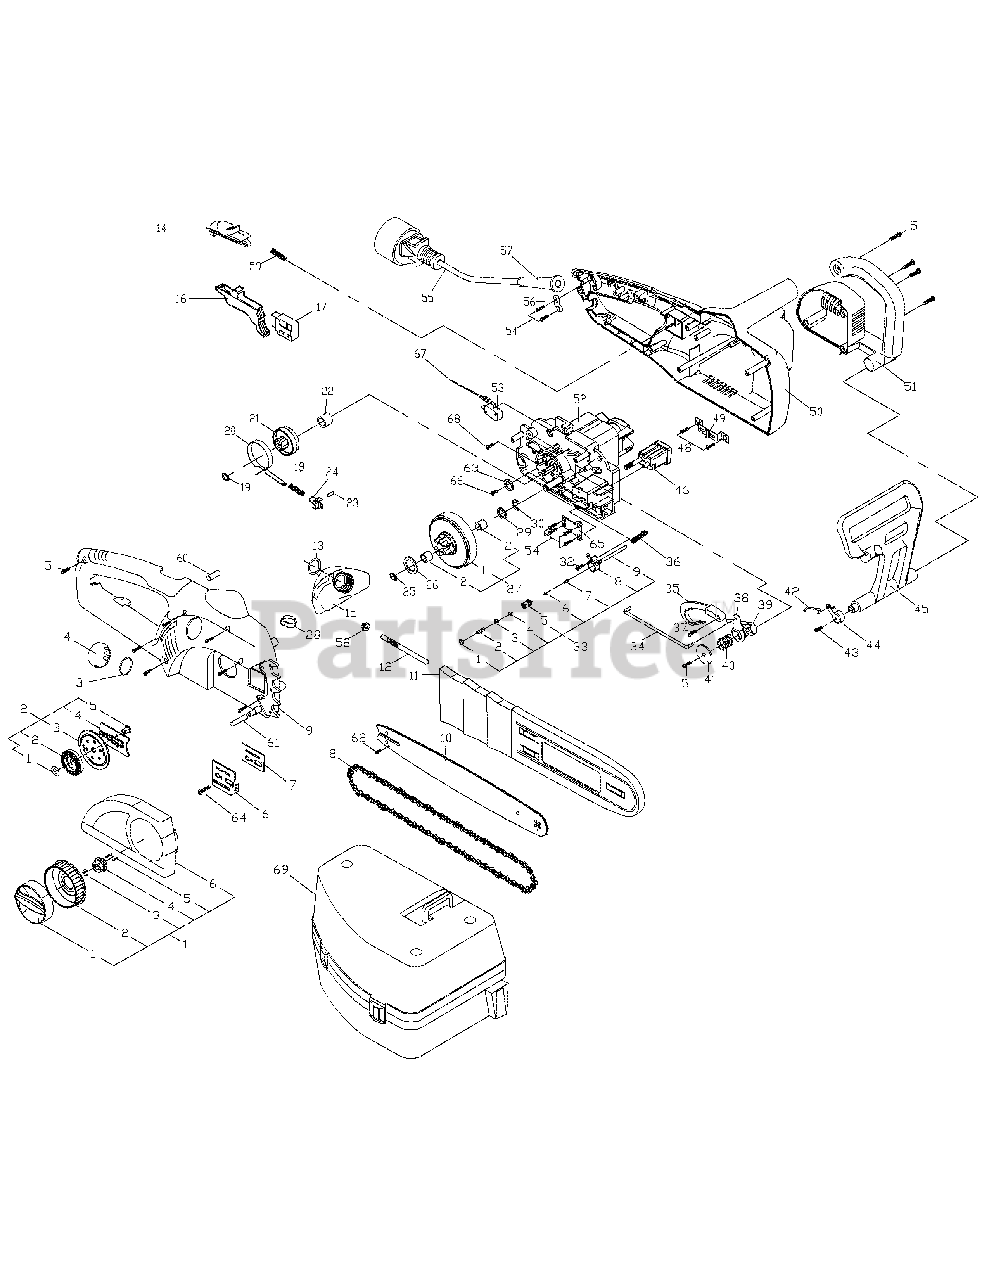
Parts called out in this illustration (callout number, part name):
1	Housing(R)
2	Chain Cover Assembly
4	Oil Cover
6	Adjustment Plate
7	Oil Washer
8	Chain Cover Assembly
9	Housing(R)
11	Cover
12	Oil Pipe Assembly
14	Switch Button
20	Spring, Brake
22	Adjusment Cover
24	Connection
27	Gear Bearing Assembly
30	C-Ring
33	Oil Pump Assembly
35	Pull Plate
42	Connecting Bar
44	Connector
45	Front-Hand Guard
46	Fixed Acc'y
50	Housing (L)
51	Real Cover
52	Motor Gear Box Assembly
55	Powercord
56	Strain Relief
57	Cord Guard
58	Rubber Stop
69	Carry Case
